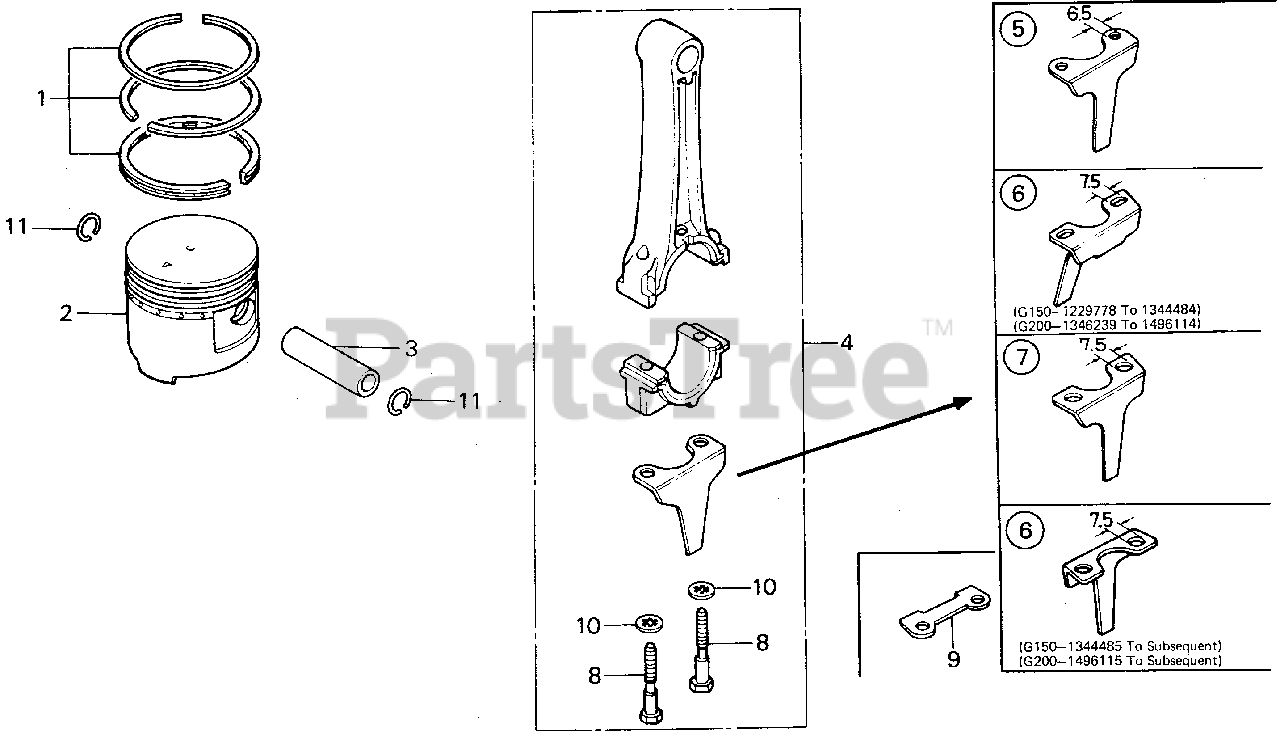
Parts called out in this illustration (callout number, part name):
1	RING SET, PISTON (STD)
1	RING SET, PISTON (OS 0.25)
1	RING SET, PISTON (OS 0.50)
1	RING SET, PISTON (0.75) (OS)
2	PISTON (STD)
2	PISTON (OS 0.25) (OS)
2	PISTON (OS 0.50) (OS)
2	PISTON (0.75) (OS)
3	PIN, PISTON
4	ROD ASSY., CONNECTING
4	ROD ASSY., CONNECTING (US) Use up to Engine SN 1167848.
4	ROD ASSY., CONNECTING (US) Use from Engine SN 1167849 to 1229777.
4	ROD ASSY., CONNECTING Use from Engine SN 1229778.
4	ROD ASSY., CONNECTING (US) Use up to Engine SN 1229777.
5	DIPPER, CONNECTING ROD (NOT AVAILABLE)
6	DIPPER, CONNECTING ROD
7	DIPPER, CONNECTING ROD (NOT AVAILABLE)
8	BOLT, CONNECTING ROD (6MM)
8	BOLT, CONNECTING ROD (6MM) (NOT AVAILABLE)
8	BOLT, CONNECTING ROD (7MM)
9	WASHER B, CONNECTING ROD
10	WASHER, LOCK (6MM) (N/A: SEE ASSEMBLY)
10	WASHER, LOCK (7MM)
11	CLIP, PISTON PIN (15MM)
